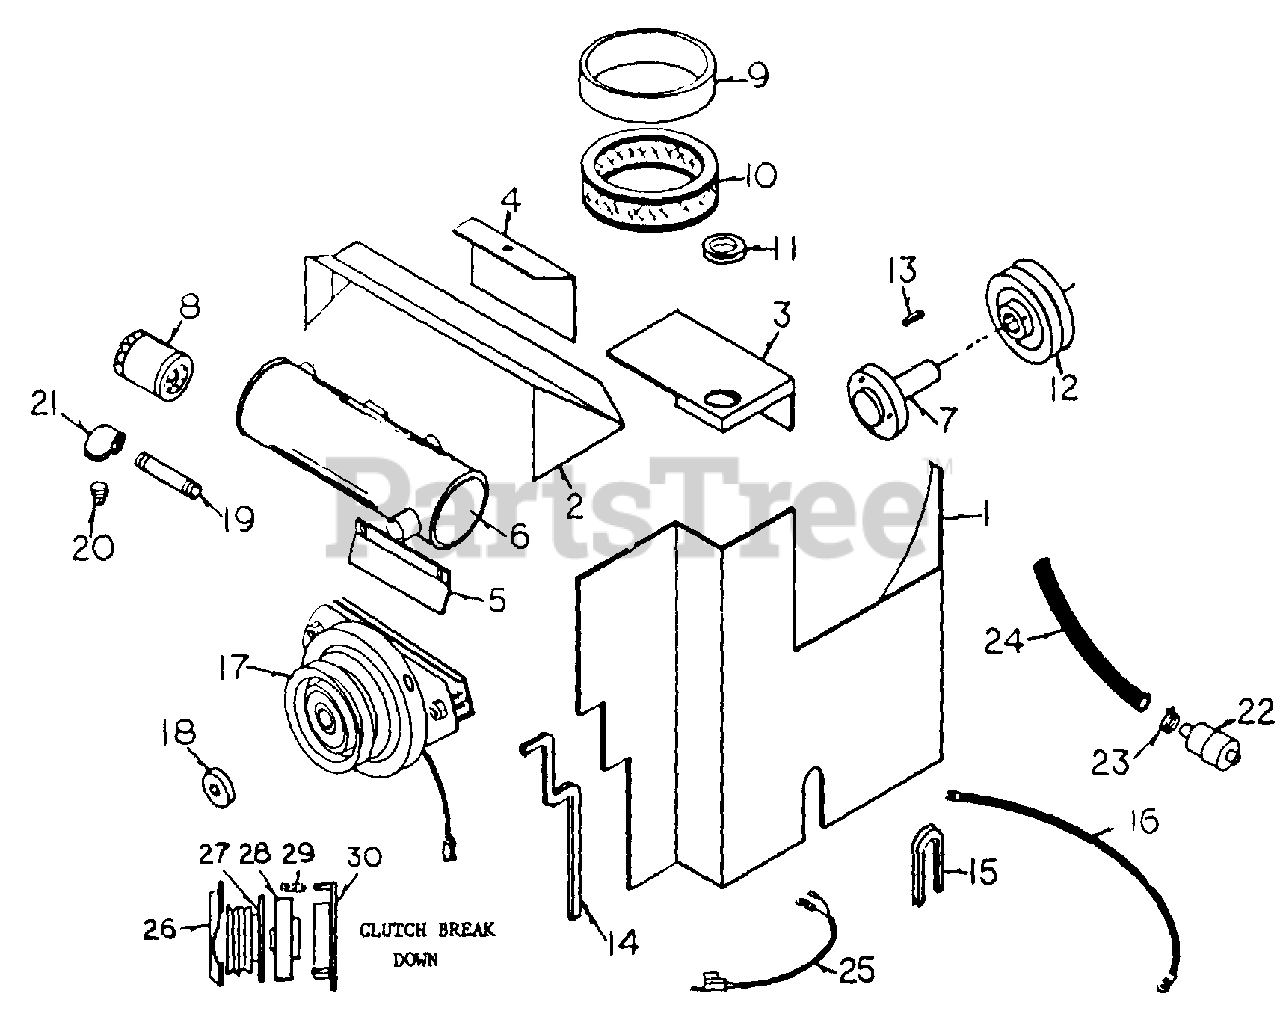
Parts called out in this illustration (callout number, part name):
1	HEAT SHIELD
2	HEAT SHIELD
3	HEAT SHIELD
4	HEAT SHIELD
6	MUFFLER - (Onan)
7	ENGINE SHAFT - (Onan)
8	OIL FILTER - (Onan)
9	PRE-CLEANER - (Onan)
10	FILTER CARTRIDGE - (Onan)
13	KEY STOCK - 1/4" x 1"
17	ELECTRIC CLUTCH
18	WASHER - clutch retainer
19	PIPE NIPPLE - 3/8"
20	PIPE PLUG - 3/8"
21	PIPE ELBOW - 3/8"
22	FUEL FILTER
23	FUEL LINE CLAMP
24	FUEL LINE - 38"
25	STARTER HARNESS
27	CLUTCH ARMATURE
29	SPRING - clutch brake
